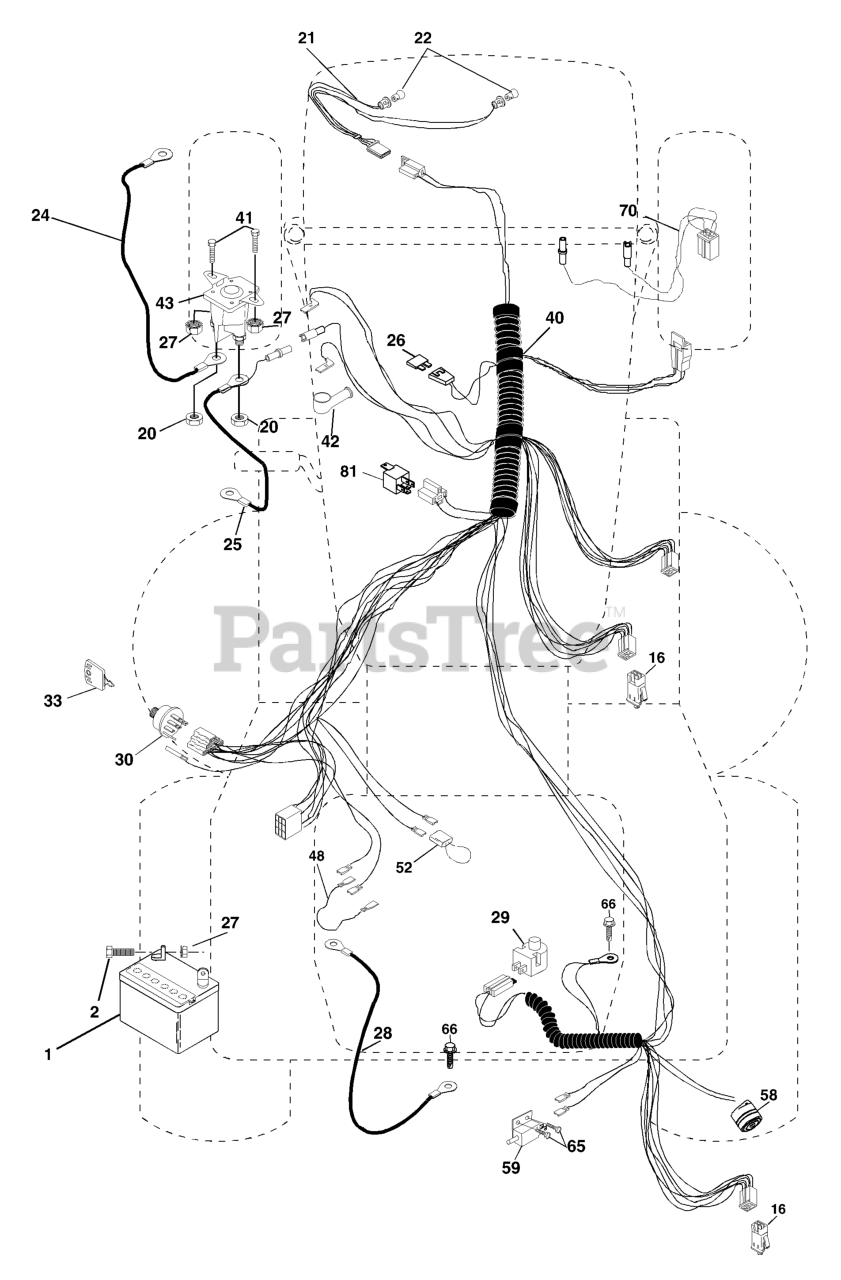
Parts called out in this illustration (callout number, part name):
1	BATTERY 12 VOLT 25 AMP
2	BOLT.HEX.1/4.X.3/4.DICHROMATE
16	SWITCH INTERLOCK
20	NUT
24	BATTERY CABLE GT
25	CABLE BATTERY
26	FUSE 15 AMP
27	NUT
28	CABLE GROUND
29	PLUNGER SWITCH (COLOR:OLIVE)
30	SWITCH IGN
33	KEY MLD GEN DELTA
40	Harness Ign Crd Noram
41	BOLT
42	TERMINAL COVER
43	SOLINOID
48	ADAPTER.AMMETER
52	WIRE PROTECTION LOOP
58	BUZZER
65	Screw Slftp #10-16 x 1/2 Ty-Ab
66	SCREW LT
70	Harness Engine B&S
81	RELAY.ASSY.T
